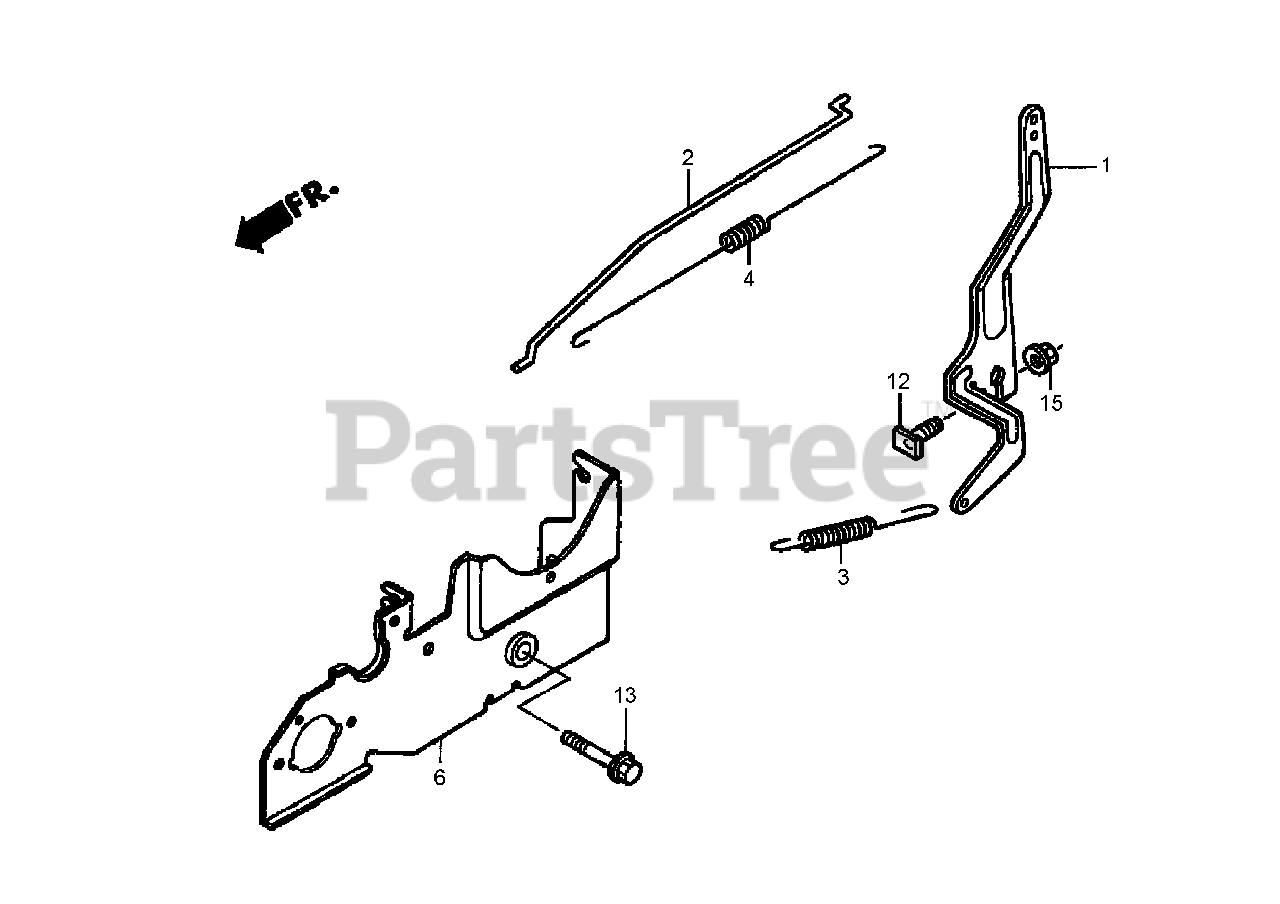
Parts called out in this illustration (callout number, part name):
1	ARM-GOVERNOR
2	ROD-GOVERNOR
3	SPRING-GOVERNOR
4	SPRING-RETURN, THROTTLE
6	BASE-CONTROL
12	BOLT-ARM, GOVERNOR
13	BOLT-FLANGE (6X45)
15	NUT-FLANGE (6MM)
